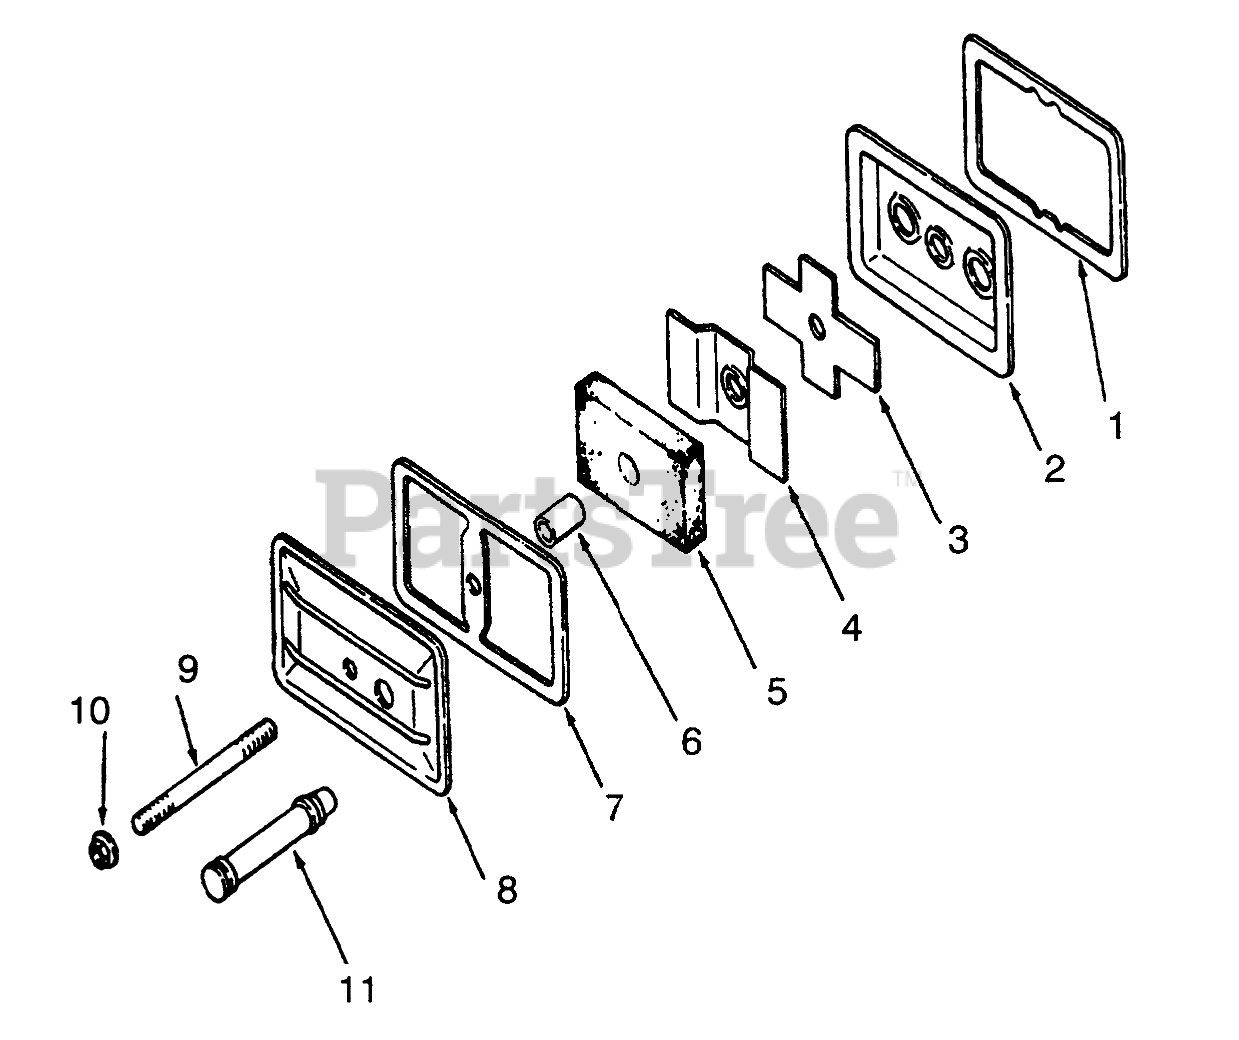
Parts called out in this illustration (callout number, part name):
1	Gasket
2	Plate
4	Baffle
5	Filter
7	Gasket
8	Cover
10	Palnut
